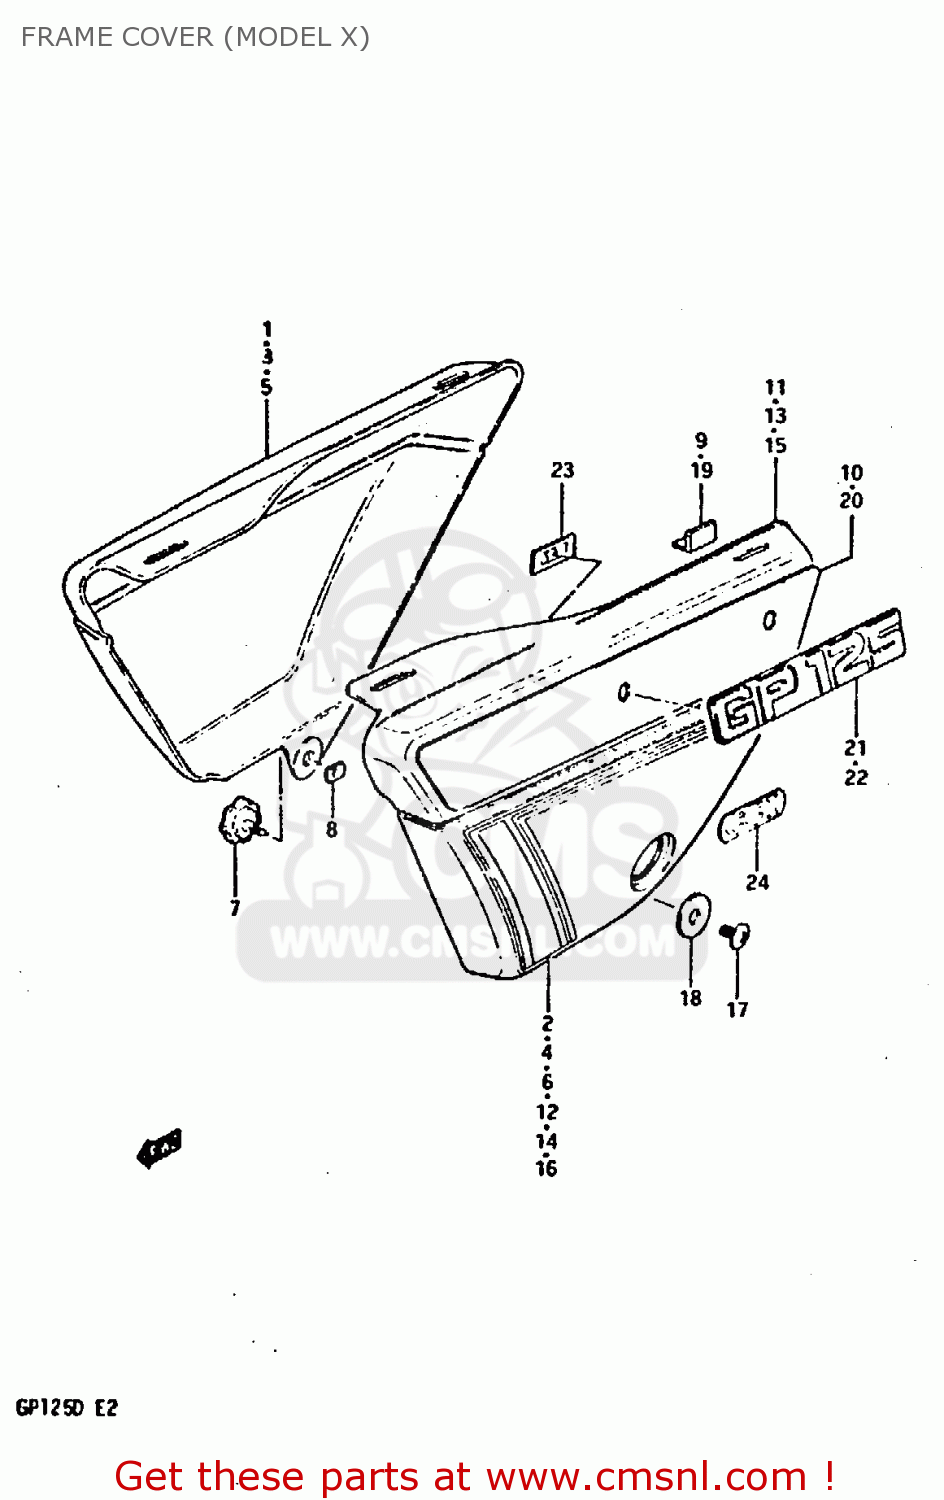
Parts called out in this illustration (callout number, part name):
1	COVER, FRAME RH
2	TAPE, RH
3	COVER, FRAME RH
4	TAPE, RH
5	COVER, FRAME RH (BLACK)
6	TAPE, RH
7	KNOB,FRAME COVER,R
8	NUT
9	CUSHION,FRAME COVER
11	COVER, FRAME LH
12	TAPE, LH
13	COVER, FRAME LH
14	TAPE, LH
15	COVER, FRAME LH (BLACK)
16	TAPE, LH
17	SCREW
18	WASHER
19	CUSHION,FRAME COVER
22	EMBLEM
23	NUT
24	EMBLEM,CCIS
